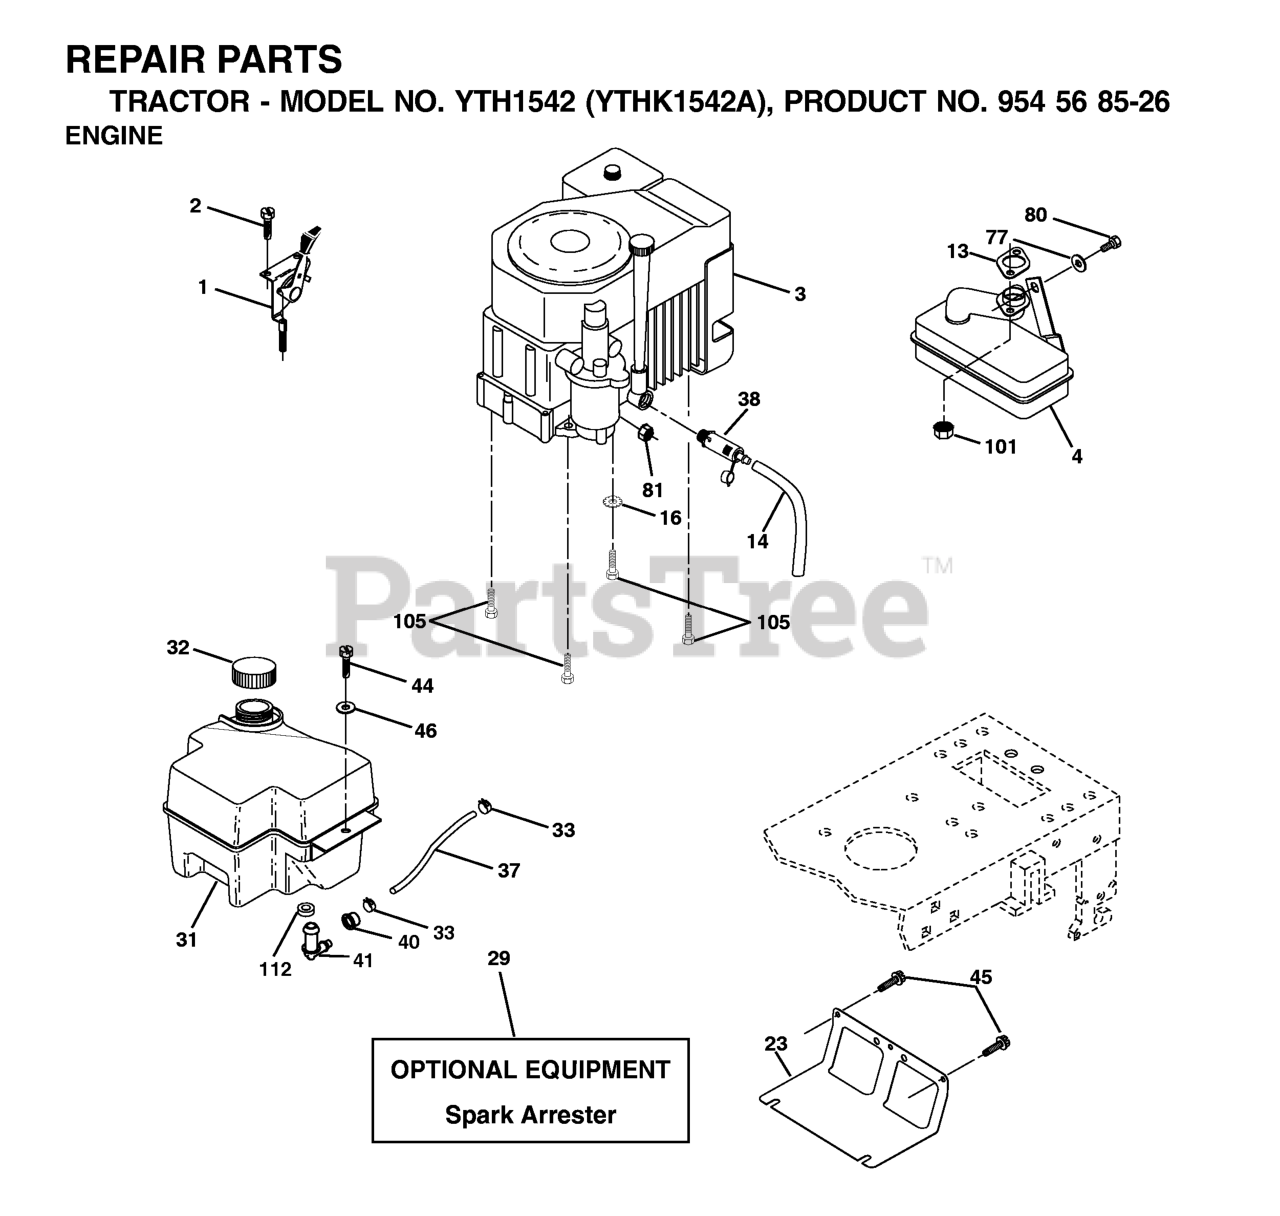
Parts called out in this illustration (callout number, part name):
1	CONTROL.THROTTLE.LT/YT
2	SCREW
4	MUFFLER.KOHL.CV.SINGLE.W/PORT
14	TUBE, DRAIN OIL ASM.
16	LOCKWASHER
23	SHIELD.BROWNING.DBR.GUARD
29	KIT.SPARK ARRESTOR 794945 B&S
31	GAS TANK 2GAL
32	FUEL CAP
33	HOSE CLAMP
37	LINE.FUEL.20
38	PLUG, OIL DRAIN EASY
40	BUSHING.SNAP.NYL.BLK.
41	STEM FUEL TANK
44	SCREW HEXWSHR 1/4-20X3/4
45	SCREW, 3/8-16X3/4
62	WASHER.LOCK.HVY.HLCL.SPR.5/16
77	WASHER
80	Bolt, Hex Head, Fin. 5/16-18 x 1/2
81	NUT
101	FLANGE NUT
105	SCREW 3/8-16X1
112	BUSHING OUTLET T
